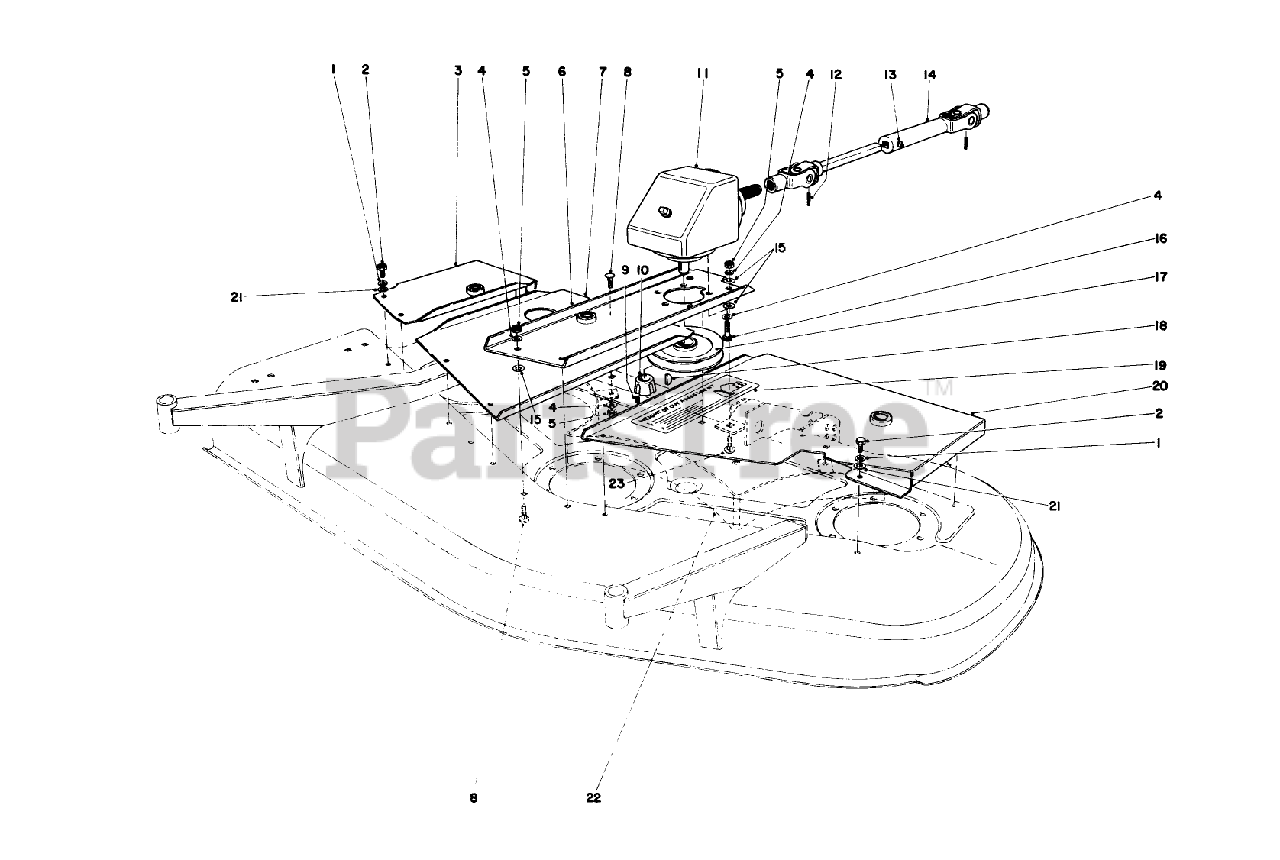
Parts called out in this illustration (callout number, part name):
1	WASHER-LOCK
2	SCREW THD 1/4 20 5/8
3	RH DECK COVER WA R
4	WASHER-LOCK
5	NUT-HEX
6	GEAR BOX BASE WA R
7	CTR DECK COVER WA R
8	SCREW-CARR
9	SCREW-SET, HSH
10	BUSHING-LOCK, TAPER
11	GEAR BOX ASM
12	PIN-ROLL
13	FITTING-GREASE
14	UNIVERSAL JOINT
15	WASHER-FLAT
16	SCREW-HSH
17	PULLEY WA BO
18	KEY-WOODRUFF
19	H O C DECAL
20	Deck Cover L.H.
21	WASHER-FLAT
22	BAFFLE WA B
23	SCREW-CARR
